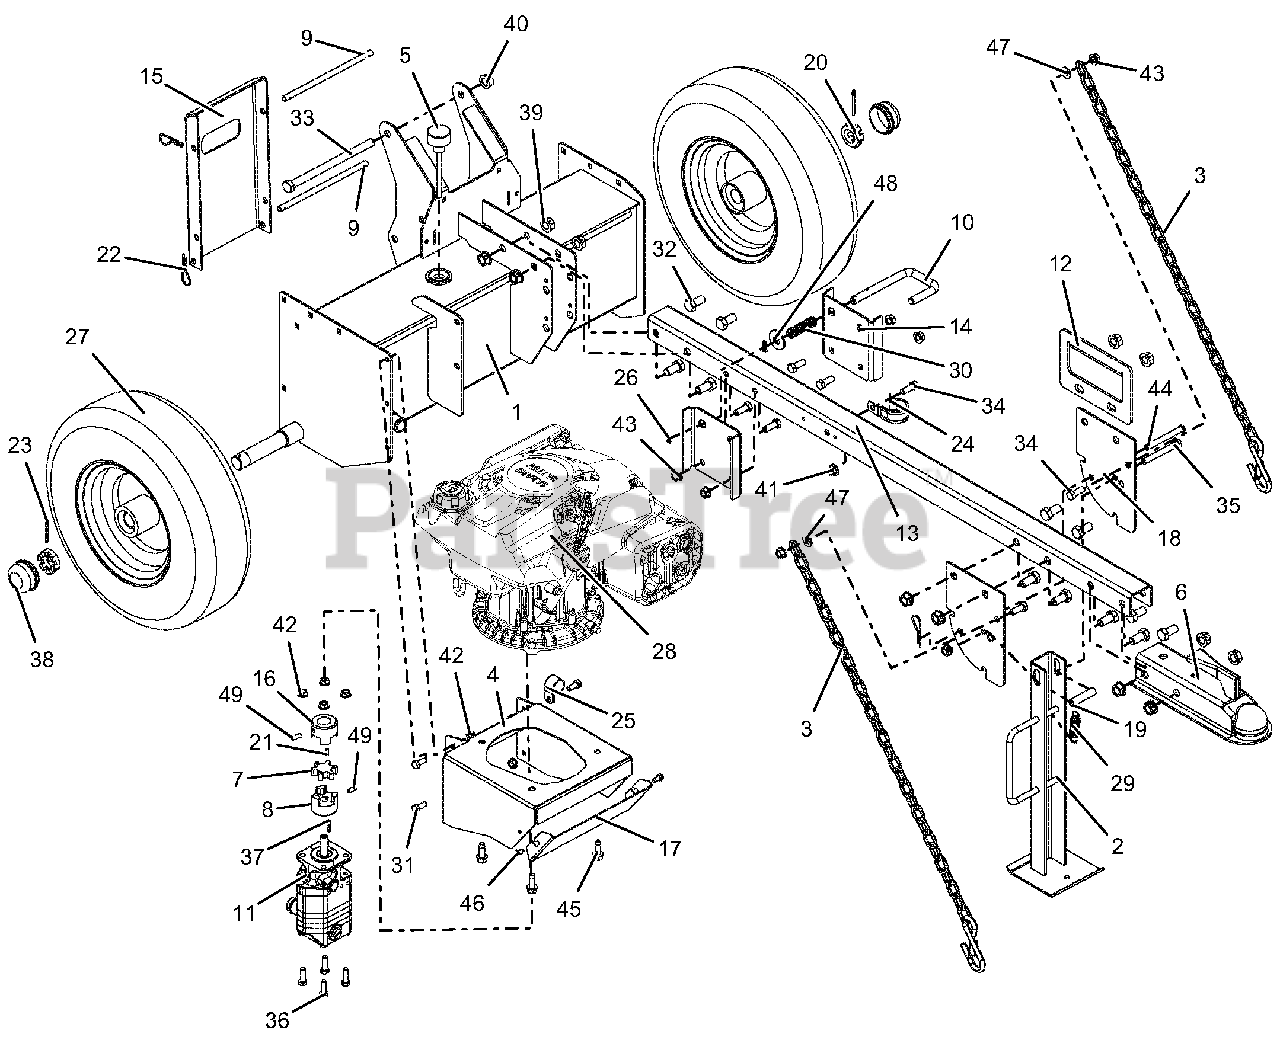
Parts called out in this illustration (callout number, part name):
1	WMT,SMALL CHASSIS
2	WLDMT, JACK STAND
3	CHAIN, SAFETY 3/16"-30LINK
4	WLDMT,ENGINE/PUMP
5	BREATHER, DIPSTICK
6	HITCH, BALL-2"
7	SPIDER - URETHANE
8	COUPLER - DRIVE 1/2"
9	PIN, .373 X 7.30 X 2X.109 THRU
10	LOCK, BEAM
11	PUMP,SPLITTER-11 GPM
12	HANDLE, SPLITTER DRAW BAR
13	BAR, DRAW
14	GUIDE, LOCK DOWN
15	SUPPORT, REAR LEG
16	COUPLER - DRIVE, 7/8"
17	COVER, COUPLING
18	MOUNT, SPRING LOADED JACK
19	SPCR, WHEEL .385X.500X2.00
20	NUT-SL 1.0-14
21	KEY-WDRF .125X.50X.20 (HRDEND)
22	HAIRPIN, #7 CLIP .094X2.31 YWZ
23	@PIN-CTR .15X1.50 YWZC
24	CLAMP, CUSHIONED STEEL 1.25
25	CLAMP, COUSHIONED STEEL REV
26	CLIP, SPRING
27	WHEEL, SPLITTER
28	ENGINE, SUBARU EA175V
29	SPRG, TENSION .063X.625X2.50
30	SPRG, COMP .058X.65X2.13 WLD15
31	@BLT-HEX .31-18X.75 GR5 YWZC
32	@BLT-HEX .50-13X1.00 GR5 YWZC
33	@BLT-HEX .50-13X7.50 GR5 YWZC
34	@BLT-HEX .38-16X1.00 GR5 YWZC
35	@BLT-HEX .38-16X3.00 GR5 YWZC
36	@BLT-HEX .31-18X1.00 GR5 YWZC
37	KEY-SQ .188X.75X.188
38	CAP, DUST
39	NUT-LK-CTR-FLG .50-13 YWZC
40	NUT-LK-CTR-FLG .50-13 YWZC
41	@NUT-LK-NYL-FLG .38-16 YWZC
42	@NUT-LK-TOP-FLG .31-18 YWZC
43	@NUT-LK-TOP-FLG .38-16 YWZC
44	PIN-CLEV .371X3.25 YWZC
45	@SCR-TAP .38-16X1.00 HWH TR YZ
46	SCR-TAP .25-20X.50 HWH TR YWZ
47	@WSHR-FL-STL.406X.812X.065 YWZ
48	@WSHR-FL-STL.563X1.38X.109YWZC
49	SCR,SET .25-20X.75 PCPT SH
